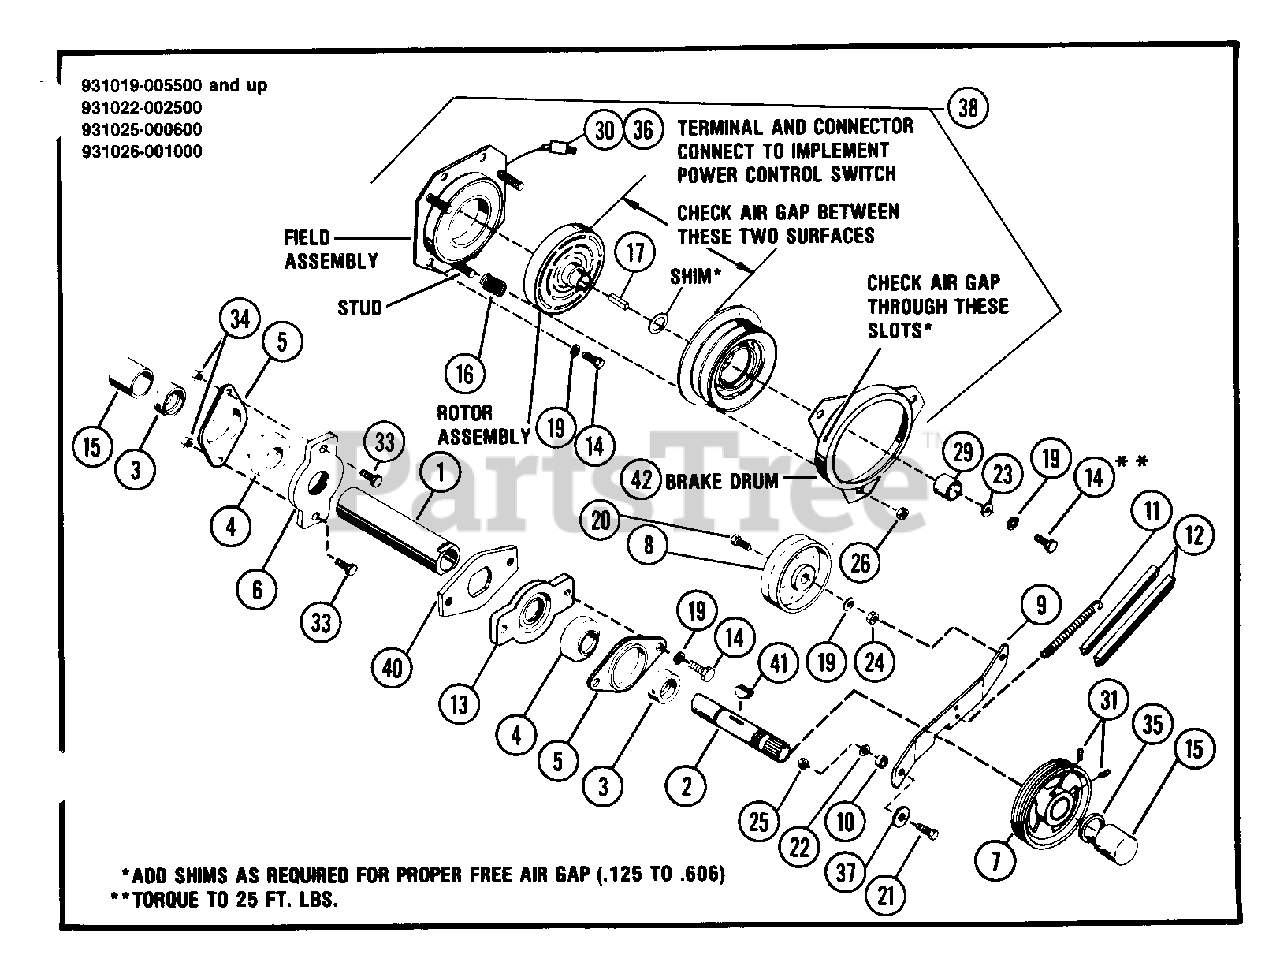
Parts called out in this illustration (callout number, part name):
1	PTO TUBE
2	FRONT PTO SHAFT
3	BEARING COLLAR
4	BRG/W COLLAR 1.0 X 2.047 X.844
6	BEARING MOUNTING FLANGE
8	IDLER-FLAT 3.218X.38
9	IDLER ARM
10	SPACER .512X.747X.208
11	SG-TENS .135X.98X6.0 WLD 62
12	V-BELT, 4L-WRAPPED (SET)
13	BEARING MOUNTING FLANGE
14	BLT-HEX .44-20X1.50 PL GR5
15	SHAFT COVER
16	SG-COMP WARNER ELEC.
17	KEY-SQ .25X.625X.25 SAE 8630
19	WSHR-LK .438X.133 HVY
20	BLT-HEX .38-16X2.00 PL GR2
21	BLT-HEX .50-13X1.25 PL GR2
22	SHIM SPACER
23	WSHR-FL-STL .515X1.625X.250
24	NUT-HEX .375-16
25	NUT-LK .50-13 PL
26	NUT-LK WARNER
29	SPACER 1.129X1.375X.855
30	MALE TERMINAL
31	SCR-SET .32-18X.38 SKHCUPNL OH
33	BLT-RDHDSQNK .38-16X1.50 PL
34	NUT-LK-CTR .375-16 GR A PL
35	RG-RTNG-EXT 1.00X.042
36	CONNECTOR BODY
37	WSHR-FL-STL .518X2.000X.105
38	CLUTCH ASSEMBLY - 1-1/4 BORE
38	CLUTCH ASSEMBLY 1-1/8 BORE
40	ANTI PIVOT PLATE
41	KEY-FTHR .25X1.25X.25 SAE
42	BRAKE DRUM
